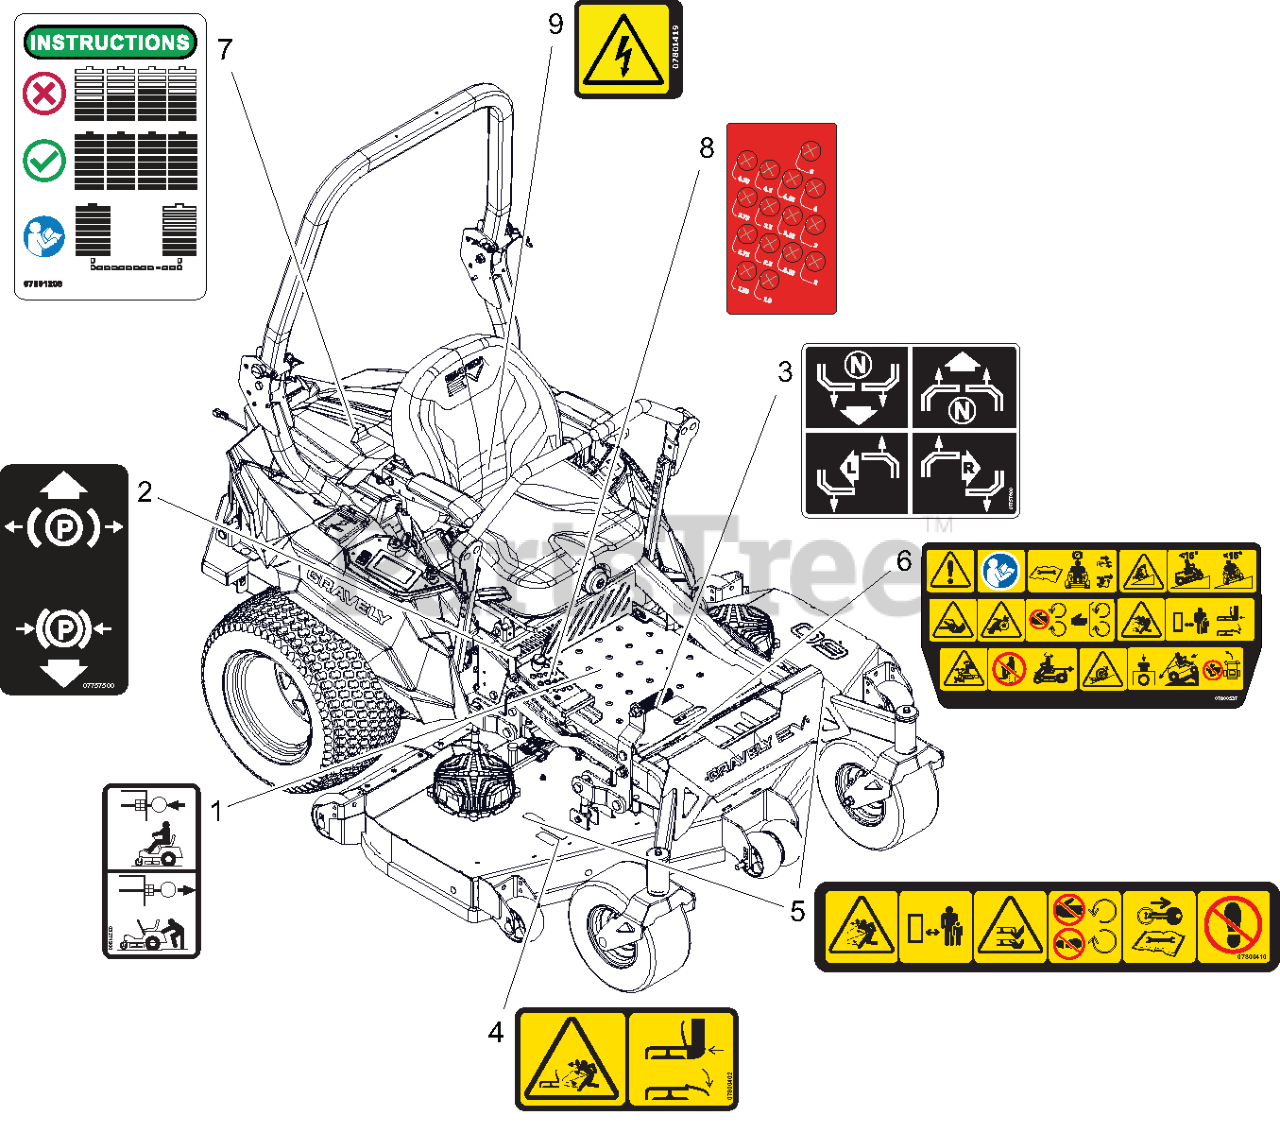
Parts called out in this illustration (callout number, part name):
1	DECAL, TRANSMISSION DISCONNECT
2	DECAL, PARKING BRAKE LEVER
3	DECAL, INSTRUCTIONAL-STEERING
4	DECAL, SAFETY - DECK GUARDING
5	DECAL, DECK SAFETY
6	DECAL, MAIN SAFETY
7	DECAL, BATTERY BALANCE
8	DECAL, HEIGHT OF CUT
9	DECAL, SAFETY - DANGER
